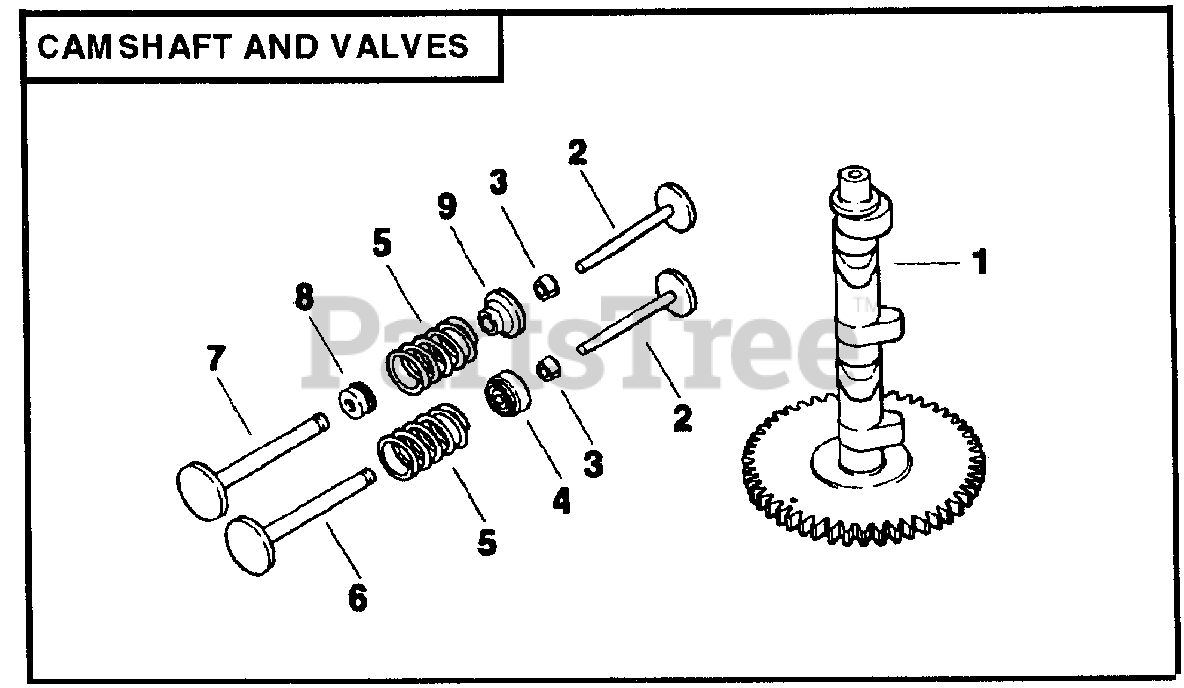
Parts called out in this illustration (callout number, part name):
6	VALVE EXHAUST
7	VALVE, INTAKE
9	RETAINER, INTAKE VALVE
